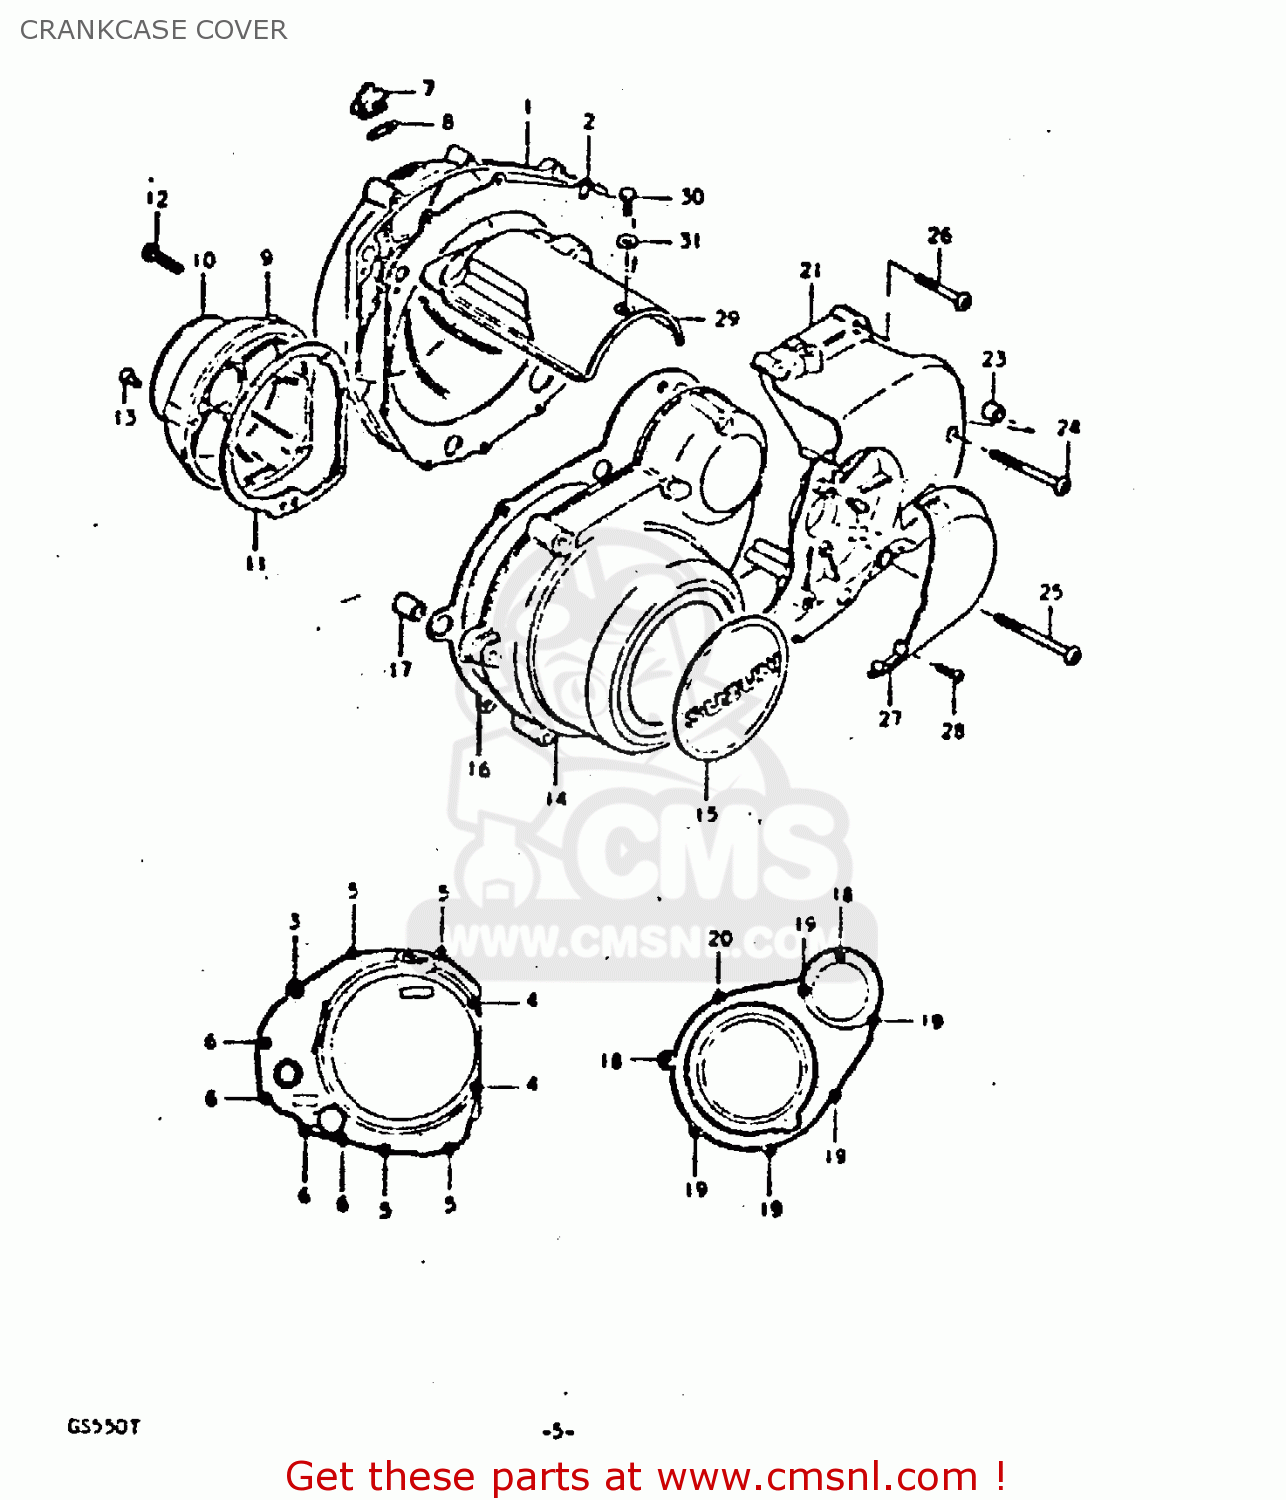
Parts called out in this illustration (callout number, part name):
1	COVER,CLUTCH
2	GASKET,CLUTCH COVER (MCA)
3	SCREW (6X35)
4	SCREW
5	SCREW
6	SCREW
7	CAP
8	O RING(D:2.2,ID:32)
9	COVER,CONTACT BREAKER
10	EMBLEM
11	GASKET,CONTACT BREAKER COVER (NAS)
12	SCREW
13	SCREW
14	COVER
15	EMBLEM
16	GASKET,MAGNETO COVER (MCA)
17	PIN
18	SCREW (6X45)
19	SCREW
20	SCREW (6X35)
21	CRANKCASE SET
22	NIPPLE
23	PIN
24	SCREW
25	SCREW 6X80
26	SCREW 6X30
27	CAP,CLUTCH RELEASE ADJUST
28	SCREW
29	COVER,STARTER MOTOR
30	BOLT
31	WASHER
